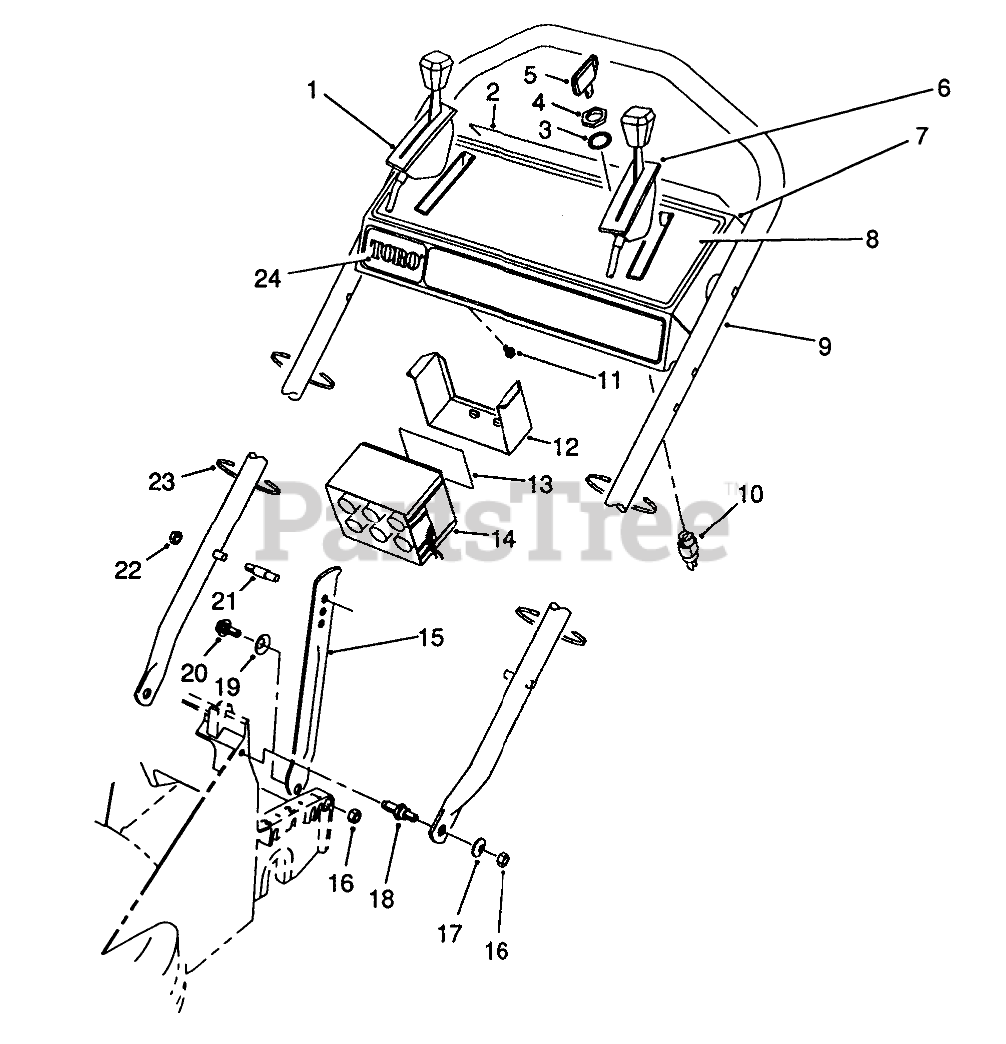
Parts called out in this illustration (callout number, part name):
1	Control-Ground Speed Bend Type #3 Sheath Lg. 51-1/4" Wire Lg. 2-1/8"
2	DECAL - PANEL, REAR
3	KEY-IGNITION
4	NUT-HH
5	WASHER-TOOTH, INTERNAL
6	ControI-Throttle Bend Type #2 Sheath Lg. 44-3/4" Wire Lg. 2-1/2"
7	Panel-Control (Incl. Ref. #8)
8	DECAL - INSTRUCTION
9	HANDLE
10	Switch-Starter (Incl. Ref. #4 & 5)
11	SCREW-HWHTF
12	Retainer-Battery
13	Decal
14	Battery (Incl. Ref. #13)
15	HANDLE LATCH
16	NUT-LOCK, NI
17	WASHER-PLAIN
18	SCREW - SHOULDER STUD
19	WASHER-BELLEVILLE
20	SHOULDER SCREW LATCH
21	HANDLE PIN
22	NUT-LOCK, NI
23	TIE-CABLE
24	DECAL - KEY LECTRIC
